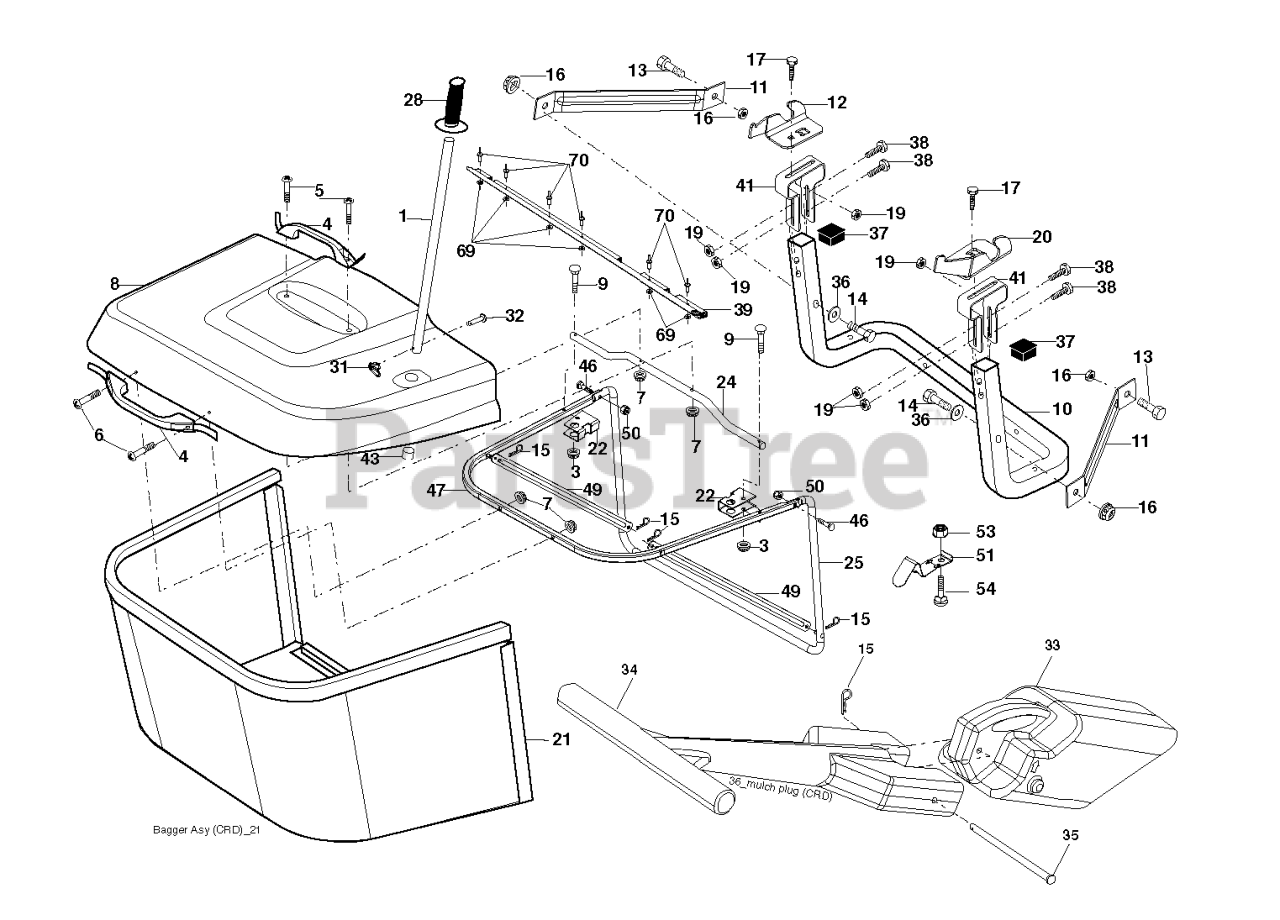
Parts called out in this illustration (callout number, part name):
1	TUBE.HANDLE.BAGGER.CRD/SRD.BLA
3	NUT T
4	HANDLE.BAGGER.W/LVRS.BLK.CRD
5	SCREW.PAN.HEAD
6	REPL BY 532 75 00-29
8	BAGGER.COVER.SEAL.ASM.
9	Bolt Carriage 1/4-20 x 2.25d x Gr.5
10	TUBE
11	BRACKET.SUPPORT.UPPER.BAG.CRD
12	BRKT PIVOT
14	BOLT-HEX EAK
15	RETAINER-SPRNG RB
16	NUT LOCK FLG 3/8-16 UNC
17	RP BOLT 5/16-18 X3/4 ZN/YEL GR
19	NUT LOCK HEX FLANGE 5/16-18
20	BRKT.PIVOT.RH.CRD
21	BAGGER.ASM.CRD.2007
22	BRACKET.BAGGER.SD.ELECTRIC.CRD
24	TUBE.PIVOT.BAG.CRD.BLACK
25	PIPE
28	GRIP.HANDLE.BLACK
31	RETAINER CLIP
32	RIVET,DRILLED
33	MULCHING.PLUG.107.CRD.(2 2)
34	HANDLE.MULCHER.92.CRD (2 2)
36	WASHER
37	Plug Support Bagger CRD
38	BOLT.5/16-18X2.5
39	SEAL.BAGGER.CRD
41	BRACKET.BAGGER.SD.ELECTRIC.CRD
43	PLUG, TUBING END
46	BOLT.CARRIAGE.5/16-18
47	PIPE
49	ROD
50	NUT.71038.31-18.HEX.NYLOCK
51	LATCH
53	NUT
54	BOLT
69	WASHER
70	RIVET RIVET POP
